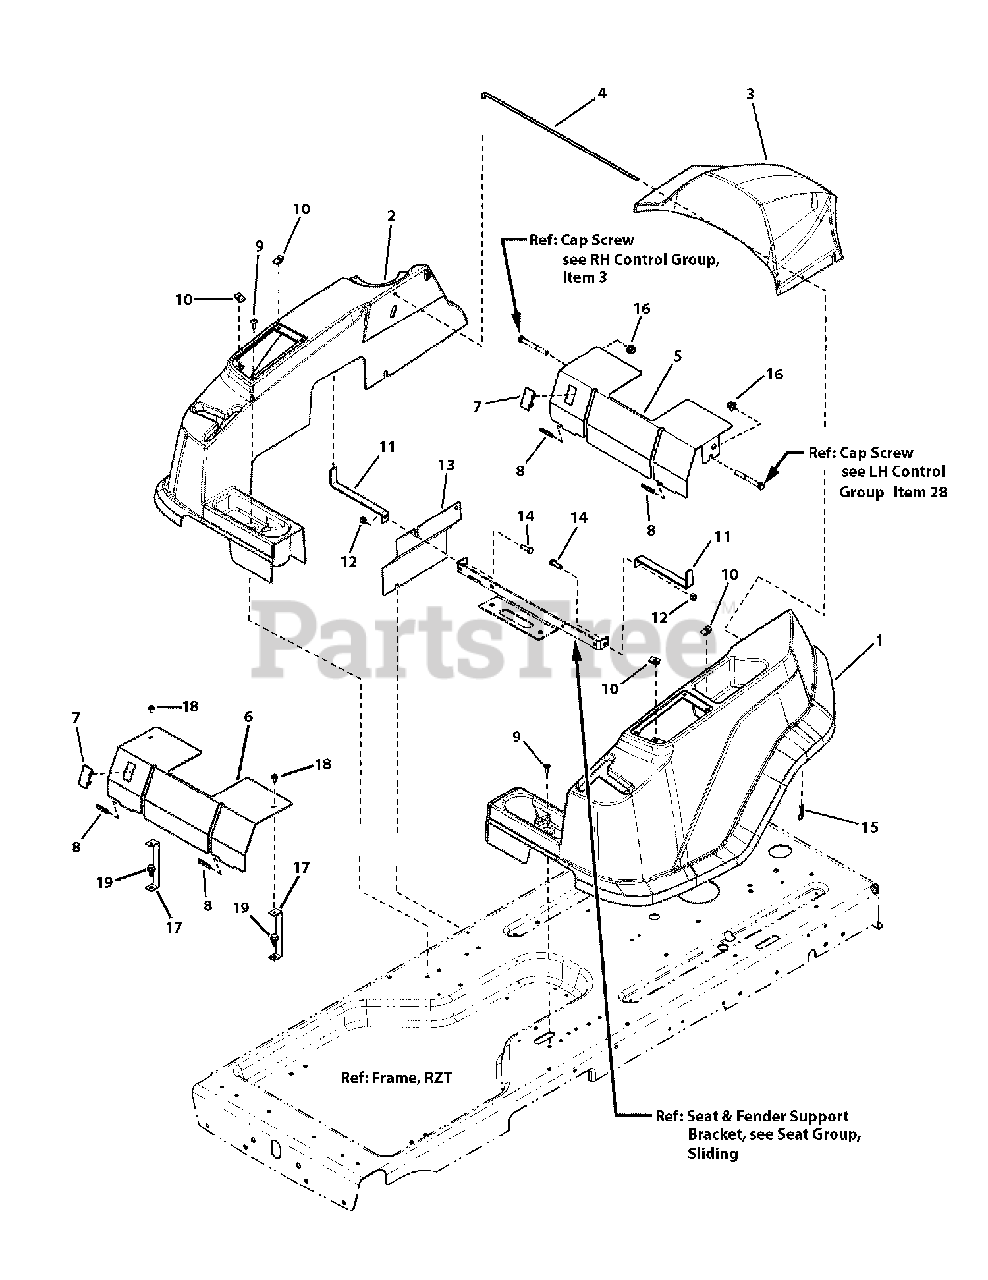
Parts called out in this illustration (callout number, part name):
1	FENDER, LH
2	FENDER, RH
3	COVER, Engine
4	ROD, Pivot, Hood
5	COVER, Battery, 285Z
6	COVER, Battery, w/Brkt Holes
7	PLUG, Switch Hole, Dash
8	STRIP, Trim, 1.50
9	SCREW, 1/4-20 x 3/4" Pan Head Self-Tap (Torx)
10	U-NUT, 1/4-20
11	BRACKET, Support, Fender
12	NUT, 5/16-18 3B Nyloc, YZ
13	PLATE, Side, RH
14	SCREW, 5/16-18 x 1" Hex Head Cap, GR 5, YZ
15	HAIR PIN, .080 Wire x 1.19 LG x .25/.38 Dia
16	NUT, 3/8-16 Hex Flange Esna, Black
17	BRACKET, Battery Cover
18	SCREW, 1/4-20 x 1/2" Hex Washer Self-Tap, BZ
19	SCREW, 3/8-16 x 3/4" Hex Washer Head Self-Tap
